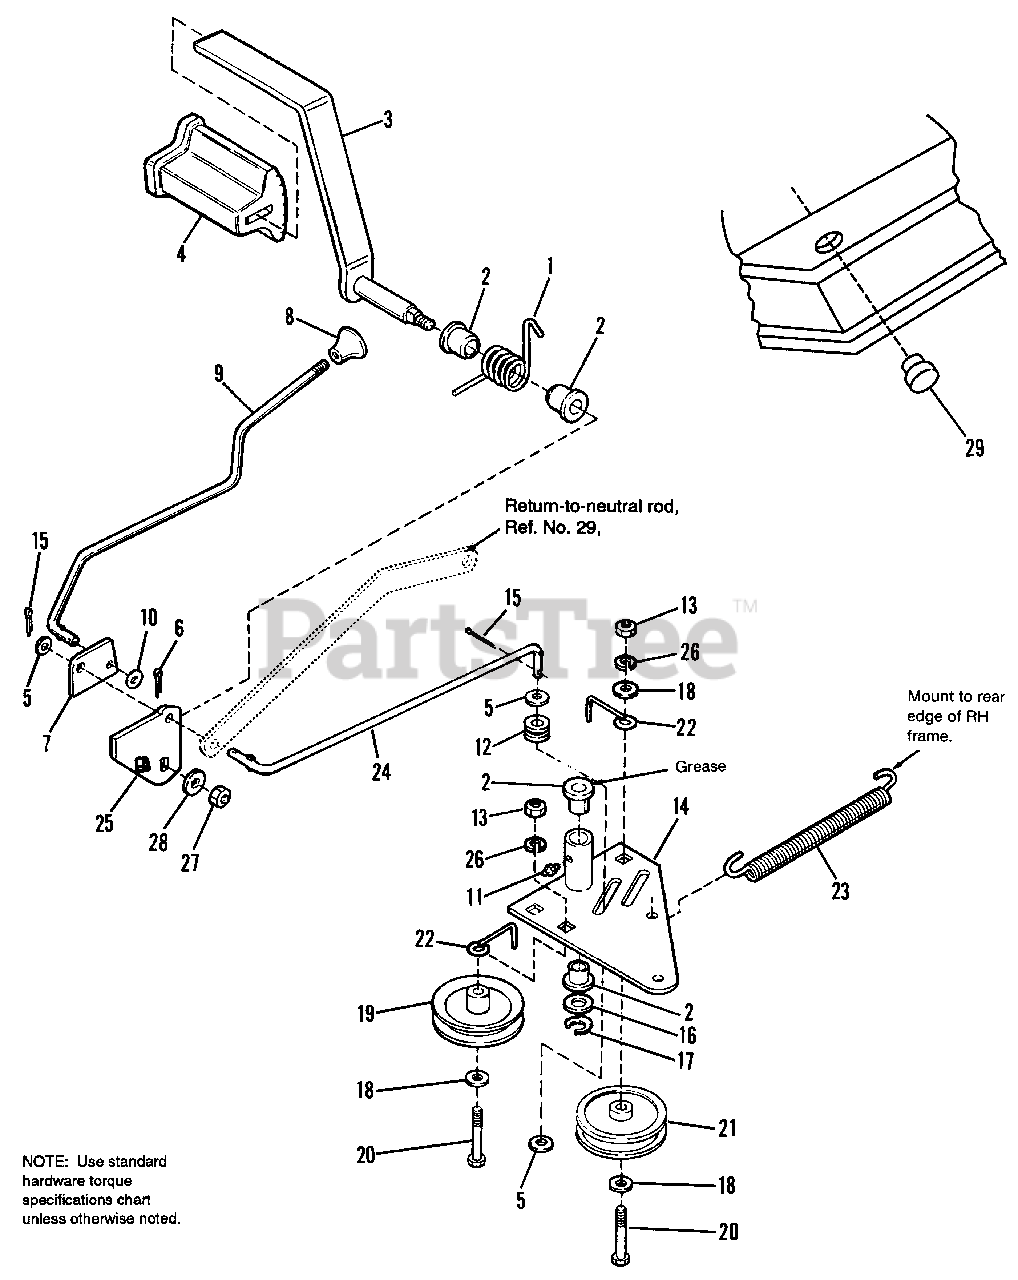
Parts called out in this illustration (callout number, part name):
1	SPRING, Torsion
3	BRAKE PEDAL ASSY.
4	PAD, Foot Pedal
5	WASHER, Plain, 11/32
6	COTTER PIN
7	CAM, Parking Brake
8	KNOB, Plastic (Mfg. Nos. 1692006, 1692036, 1692042, 1692044)
8	KNOB, Soft (Mfg. Nos. 1692440, 1692442, 1692446, 1692448,1692502)
9	ROD, Parking Brake
10	WASHER, Plain, 9/32
11	FITTING, Grease
13	NUT, Hex, Full, 3/8-16
14	IDLER ARM ASSY.
15	PIN, Cotter
16	WASHER, 5/8
17	KLIP RING, 5/8
18	WASHER, Plain, 13/32
19	PULLEY, Flat, Idler
20	CAPSCREW, 3/8-16 x 2
21	PULLEY, "V"
23	SPRING, Tension
24	ROD, Clutch
25	ARM, Foot Pedal
26	LOCKWASHER, 3/8
27	NUT, Hex, Lock, 3/8-16
28	WASHER
29	TUBE, Closure
